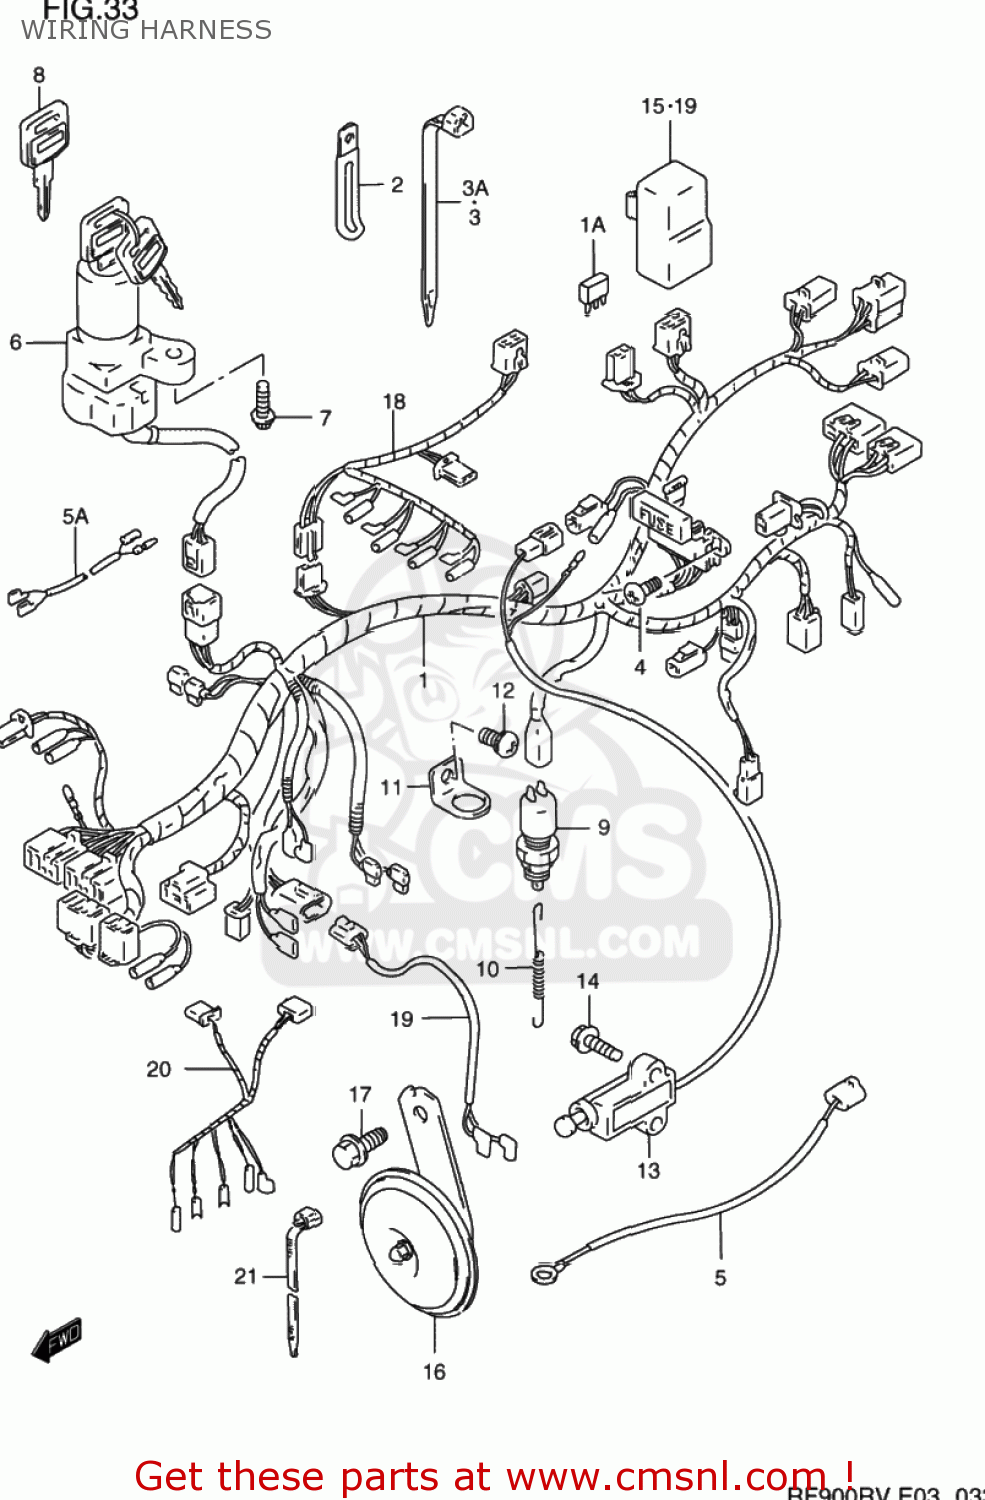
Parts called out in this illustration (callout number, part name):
1	HARNESS,WIRING
1A	DIODE(STANLEY DE8804)
2	CLAMP
3	CLAMP L:165
3A	CLAMP(L:90)
4	SCREW 6X12
5	WIRE,OIL PRESSURE SWITCH LEAD
5A	WIRE,CLUTCH LEAD
6	LOCK ASSEMBLY,STEERING
7	SCREW(6X18)
8	KEY,BLANK
9	SWITCH ASSY,STOP LAMP
10	SPRING
11	BRACKET,STOP LAMP SWITCH
12	SCREW
13	SWITCH ASSY,SIDE STAND
14	BOLT
15	RELAY ASSY
16	HORN ASSEMBLY,LOW PITCH
17	BOLT
18	WIRE,CARBURETOR HEATER LEAD
19	RELAY ASSY
20	WIRE,CARB HEATER LEAD
21	CLAMP(L:125)
